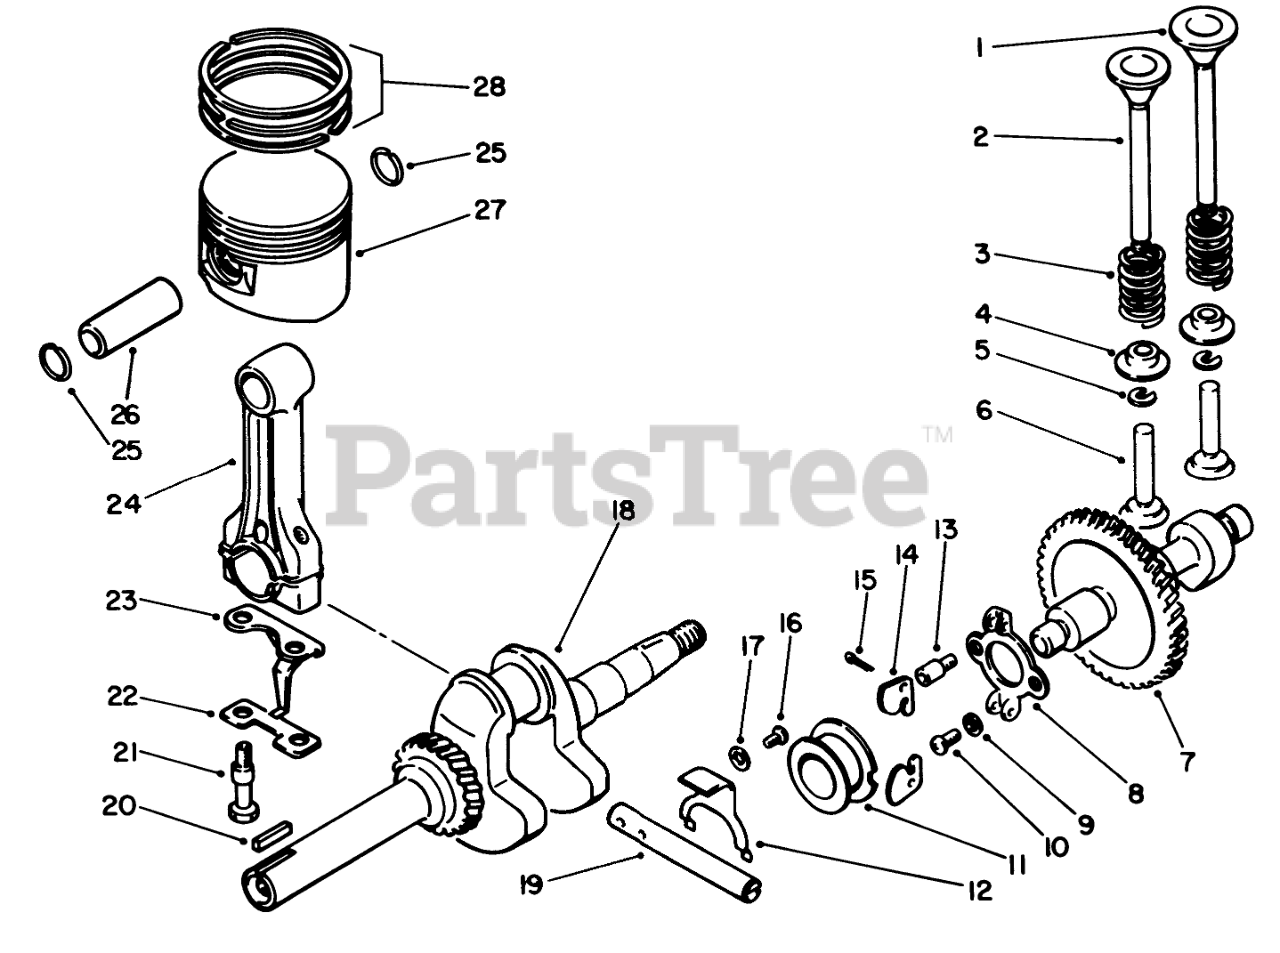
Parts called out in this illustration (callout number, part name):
1	VALVE, INTAKE
2	VALVE, EXHAUST
3	Spring-Valve
4	Retainer-Spring
5	Cotter-Valve
6	TAPPET
7	Cam Shaft
8	BRACKET
9	Washer
11	Spacer
12	SHIFT PLATE
14	BRACKET
15	Cotter Pin
16	SCREW
17	Washer
18	Crankshaft Assembly
19	SHAFT-THROTTLE TURN
22	LOCK PLATE
23	Plate-Splasher
24	Connecting Rod Assembly (Incl. Ref. #21-23)
25	CIRCLIP
26	Pin Piston
27	Piston Std.
28	Ring Set-Piston Std.
